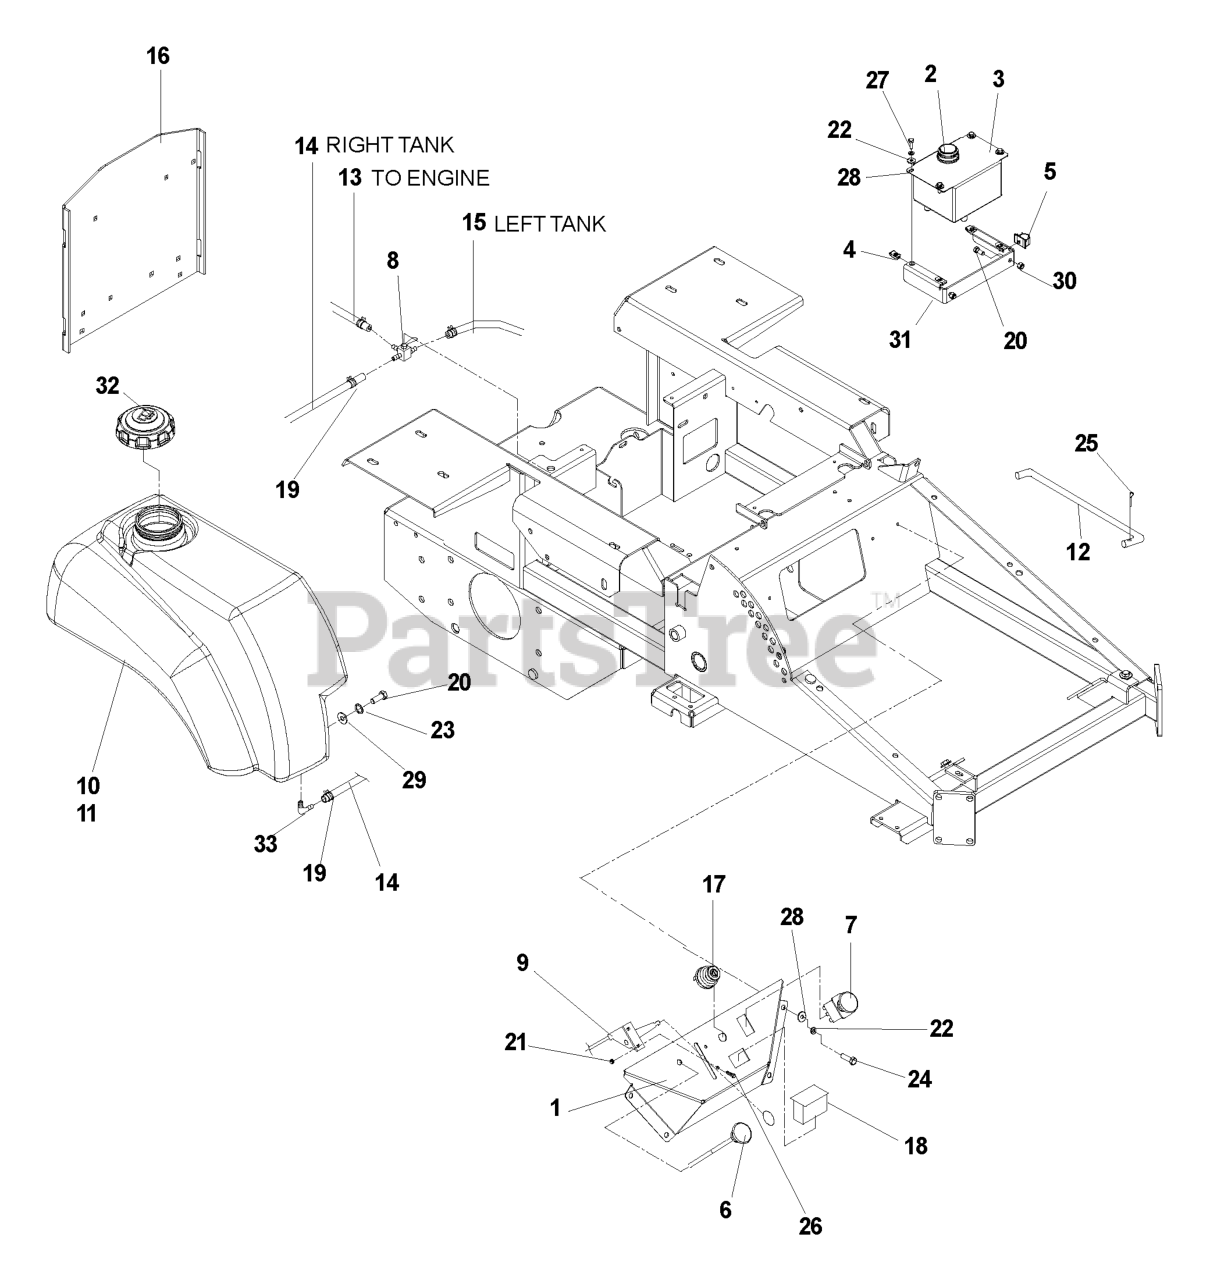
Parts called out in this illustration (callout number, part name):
1	CONSOLE W/DECALS
2	CAP-HYDRO RESERVOIR
4	RETAINER, U TYPE
5	PUSH-MOUNT WIRE CLIP
6	CHOKE CABLE
7	SWITCH
8	VALVE, FUEL
9	CONTROL, THROTTLE
10	TANK, FUEL, LEFT
11	TANK, FUEL, RIGHT
13	FUEL LINE
14	FUEL LINE
16	ENGINE GUARD
17	IGNITION SWITCH
18	HOUR METER
19	CLAMP, HOSE
20	HCS, 5/16-18 X 3/4, GR5
21	NUT, #10-24, NYLOC
22	LOCKWASHER, 1/4
23	LOCKWASHER, 5/16
24	SCREW, 1/4-20 X 5/8, SELF TAP
25	PIN COTTER, 1/8 X 3/4
26	SCREW, #10-24 X 1/2
27	HCS, 1/4-20 X 3/4, GR5
28	WASHER, 1/4
29	WASHER, 5/16
30	NUT, 5/16-18, NYLOC
31	TANK MOUNT
32	FUEL CAP, ANTISPLASH
33	TANK FITTING
